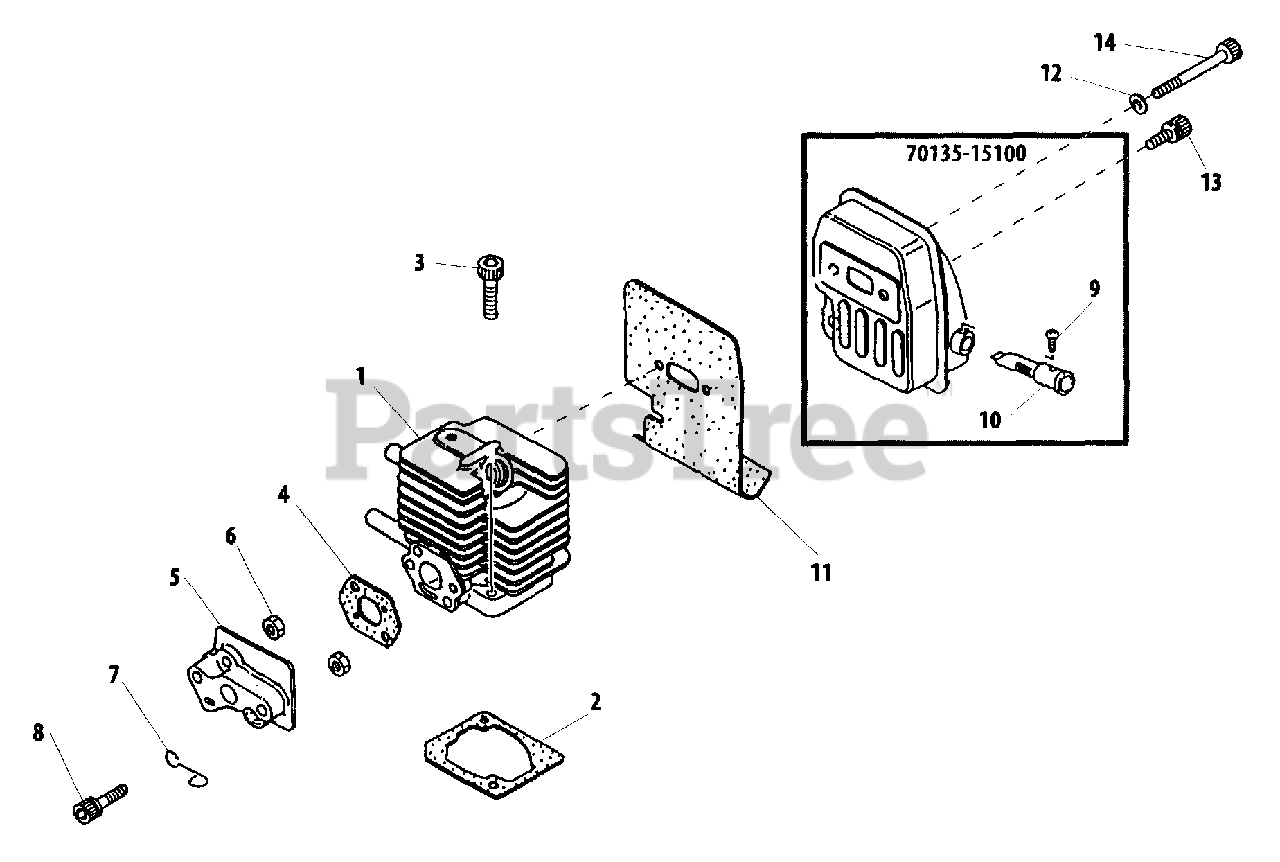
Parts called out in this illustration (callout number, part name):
1	CYLINDER
2	GASKET, CYLINDER
3	SCREW - 5X25
4	GASKET
5	INSULATOR
6	NUT
7	HOLDER, VENT
8	SCREW - 5X25
9	SCREW - 3X6
10	SCREEN, SPARK ARRESTOR
11	SHIELD, EXHAUST
12	WASHER - 5
13	SCREW - 5X12
14	SCREW - 5X50
70135-15100	MUFFLER ASSY
